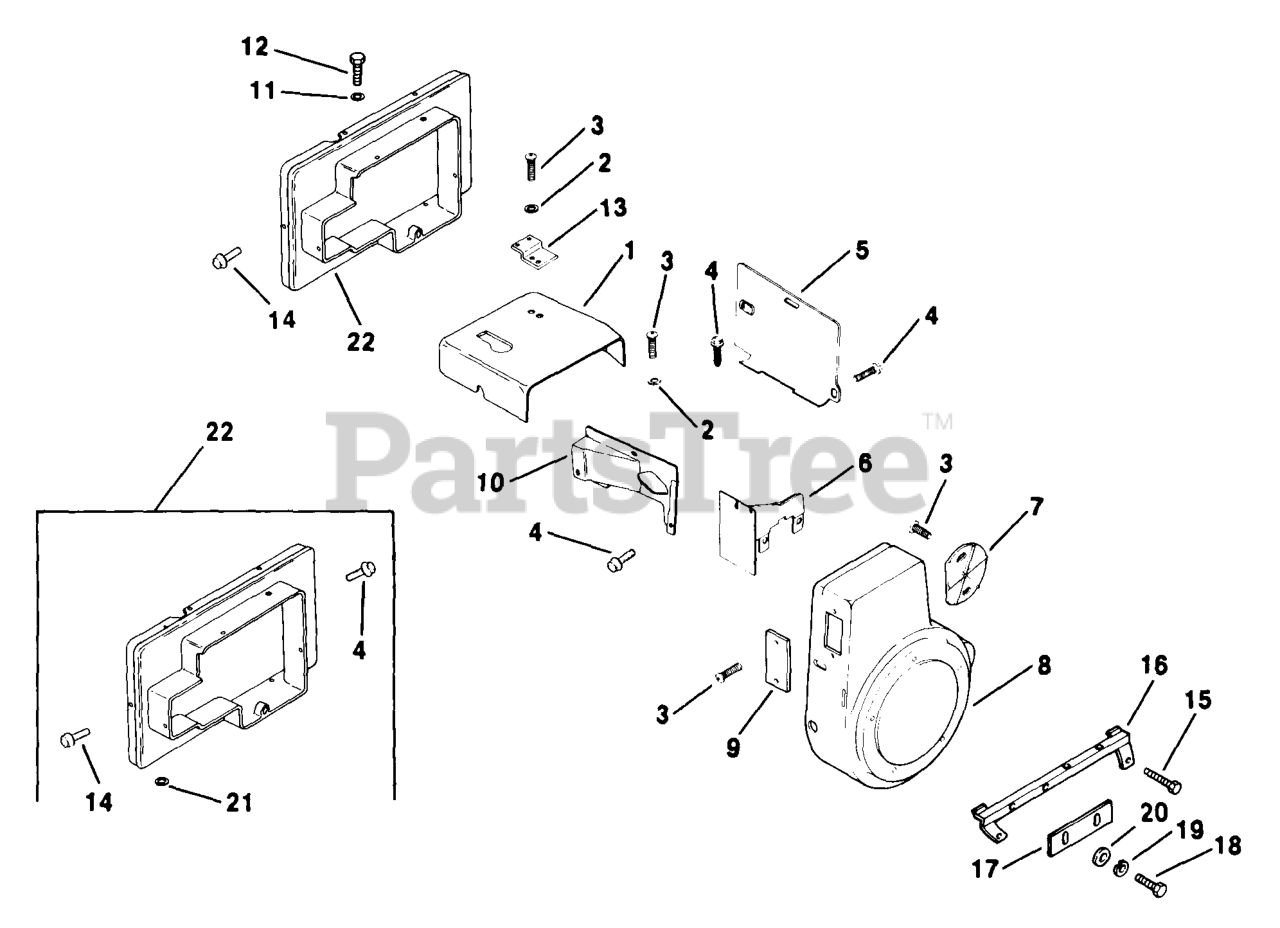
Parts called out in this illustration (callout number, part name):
2	WASHER, FLAT 1/4" (O.D. 5/8")
3	SCREW, POZ TRS HD 1/4-20X5/8" - DISCONTINUED
4	SCREW, WSH HD TAP 1/4-20-5/8" - DISCONTINUED
5	BAFFLE, CYLINDER
6	BAFFLE, INNER - DISCONTINUED
8	HOUSING - USE 47 027 44
10	BAFFLE, SIDE AIR - DISCONTINUED
